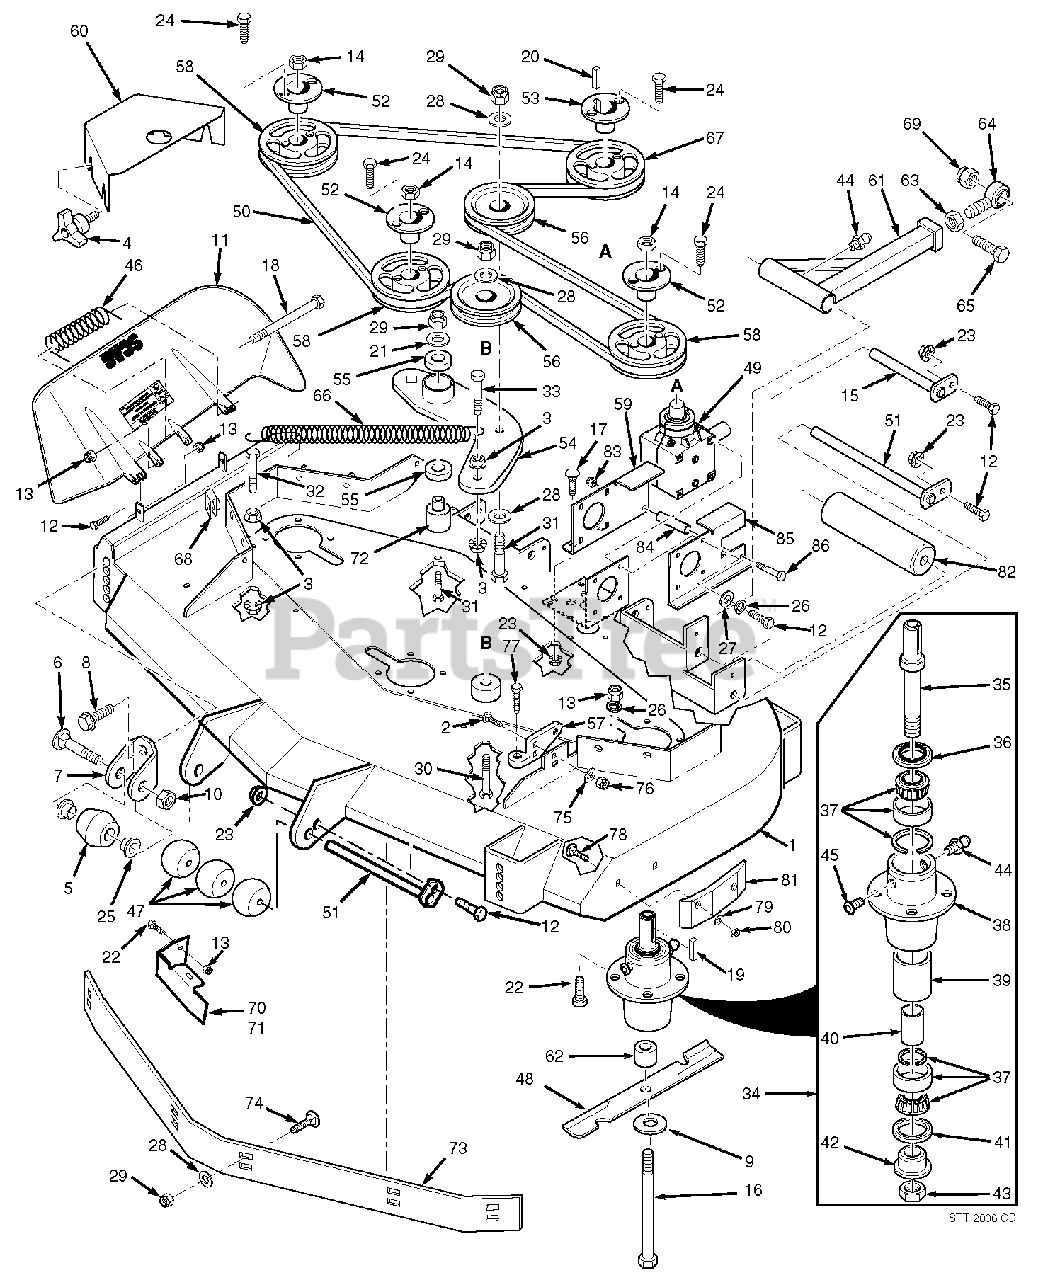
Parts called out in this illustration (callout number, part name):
1	Cutter Deck Velocity Plus
2	Bolt, Carriage 7/16-14 x 1-1/4"
3	Nut, Hex Serr. Flng 3/8-16
4	Wing nut, 3/8-16
5	Anti-Scalp Wheel
6	Bolt, Carriage 3/8-16 x 4"
7	Anti-Scalp Wheel Bracket
8	Bolt, Hex Serr. Flng 3/8-16 x 1"
9	Flatwasher, 5/8" Hardened
10	Locknut, 3/8-16 Center Lock
11	Discharge Chute
12	Bolt, Hex Head 5/16-18 x 1-3/4" - Front
12	Bolt, Hex Head 5/16-18 x 1-1/2" - Rear
13	Nut, Hex Elastic Stop 5/16-18 Grd 8
14	Nut, 5/8-11 UNC
15	Push Arm Shaft
16	Bolt, HH 5/8-11 x 9-1/2"
17	Bolt, Carriage 5/16-18 x 3/4"
18	Bolt, HH 5/16-18 x 4-1/2"
19	Key, 1/4 x 1/4 x 2"
20	Key, 1/4 x 1/4 x 1-1/4"
21	Flatwasher, 3/8" (.39 x .938 x .105") HD
22	Bolt, HH 5/16-18 x 1-3/4"
23	Nut, Hex Serr. Flng 5/16-18
24	Bolt, HH 1/4-20 x 1" Grd 8
25	Bushing, .376" I.D. Oilite
26	Lockwasher, 5/16"
27	Flatwasher, 5/16" (.375 x .875 x .083")
28	Flatwasher, 3/8" (.391 x .938 x .105")
29	Nut, Hex Elastic Stop 3/8-16
30	Bolt, HH 3/8-16 x 3-1/4"
31	Bolt, HH 3/8-16 x 3"
32	Bolt, HH 3/8-16 x 1-1/2"
33	Bolt, HH 3/8-16 x 1-1/2" Grd 8
34	Spindle Assembly
35	Spindle Shaft
36	Seal, Top
37	Bearing Assembly
38	Spindle Housing
39	Spacer, Outside
40	Spacer, Inside
41	Seal, Bottom
42	Spindle Bushing, Bottom
43	Nut, Special 1-1/16-18
44	Grease Fitting
45	Relief Fitting, Tapered Spindle
46	Spring, Discharge Chute
47	Wheel, Anti-Scalp
48	Cutter Blade, 18"
49	Gearbox Assm, Deck Drive
50	Belt, Cutter Deck Drive
51	Roller Shaft
52	Tapered Hub, 1-1/8" Bore
53	Tapered Hub, 1" Bore
54	Idler Arm, Cutter Deck
55	Bearings, Ball
56	Pulley, Idler
57	Lever Assembly, Deck Level
58	Pulley, 5.75" O.D. (52")
59	Mounting Plate, RH Gearbox
60	Belt, Cover
61	Pusharm
62	Spacer, Spindle Bottom
63	Nut, Hex Head 5/8-18 UNF
64	Rod End, 5/8" Male RH Thrd
65	Bolt, Hex Head 5/8-11 x 4-1/2"
66	Spring, Cutter Deck
67	Pulley, 6.95" O.D.
68	U-Nut, 3/8-16
69	Nut, Hex Elastic Stop 5/8-11
70	Discharge Baffle 52V
72	Pivot, Idler - Short
73	Baffle, Custom Cut 52V
74	Bolt, Carriage 3/8-16 x 1"
75	Flatwasher, 7/16" (.500 x 1.25 x .083")
76	Nut, Elastic Stop 7/16-14
77	Bolt, Deck Adjust
78	Bolt, Carraige 5/16-18 x 3/4"
79	Flatwasher, 5/16"
80	Nut, Center Lock 5/16-18
81	Wear Pad
82	Wheel, Anti-Scalp
83	Nut, Elastic Stop 5/16-18
84	Spacer, Gearbox Mount
85	Mounting Plate, LH Gearbox
86	Bolt, HH 5/16-18 x 4-3/4"
